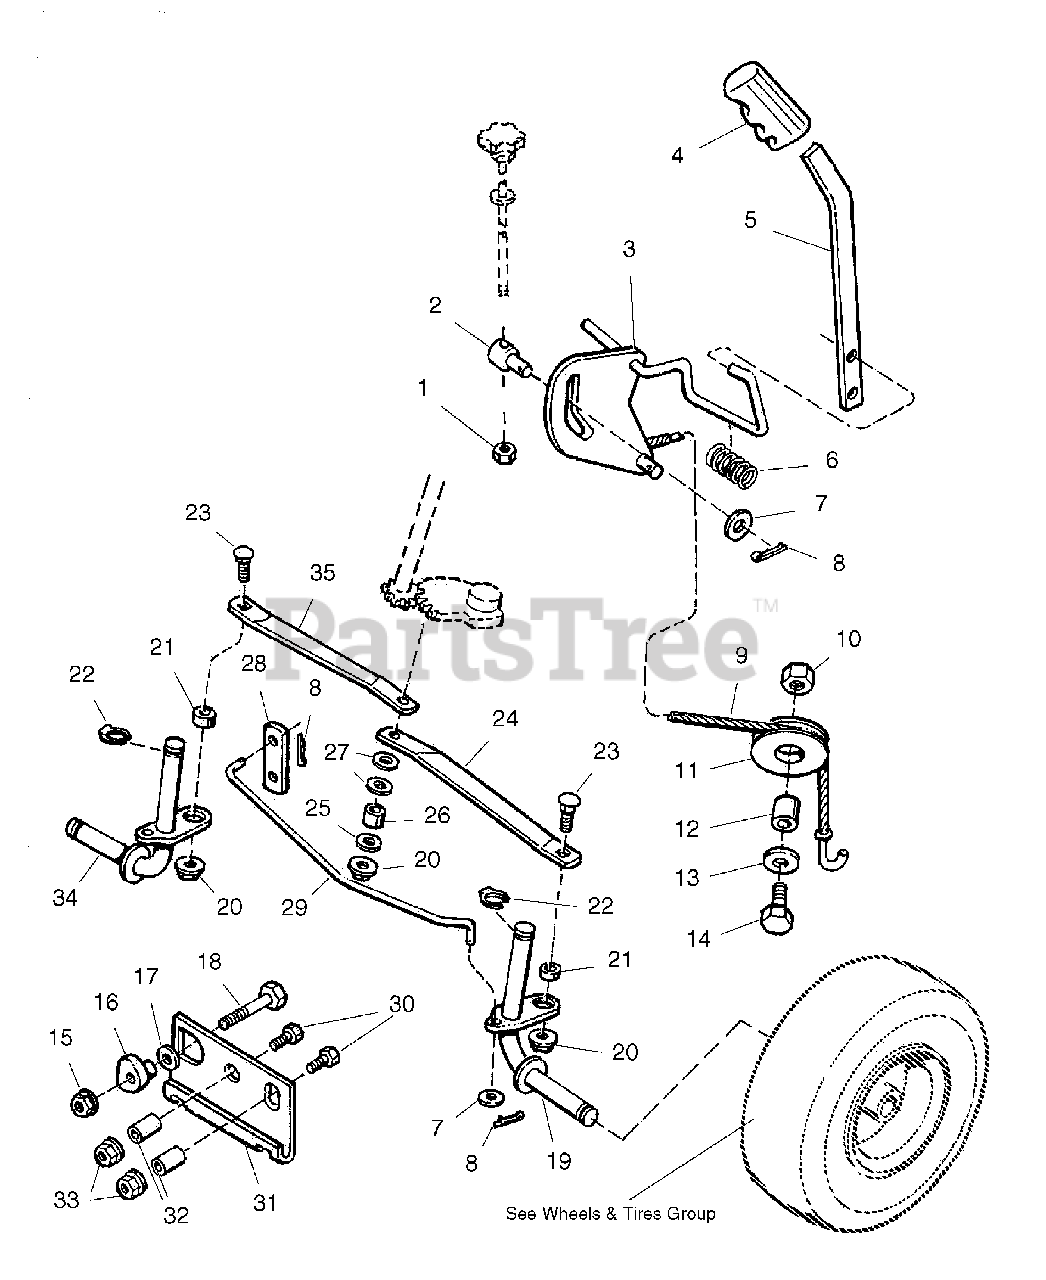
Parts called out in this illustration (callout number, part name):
1	NUT, Hex, 3/8-16
3	ARM ASSEMBLY, Lift
4	GRIP, Lever
5	LEVER, Lift
6	SPRING, Compression
7	WASHER, Plain, 13/32 x 7/8 x 5/64
8	COTTER PIN, 3/32 x 3/4
9	CABLE ASSEMBLY, Lift
10	NUT, Hex, Esna Lock, 3/8-16
11	PULLEY, Lift
13	WASHER, Plain, 13/32 x 1-1/2 x 1/8
14	CAPSCREW, Hex Head, 3/8-16 x 1-1/2
15	NUT, Hex, Flange Lock, 3/8-16
17	WASHER, 13/32 x 7/8 x 1/8
18	CAPSCREW, Hex Head, 3/8-16 x 1-3/4
19	SPINDLE ASSEMBLY, LH
20	NUT, Hex, Flange Lock, 5/16-18
23	CARRIAGE BOLT, 5/16-18 x 1-1/4
24	TIE ROD, LH
25	WASHER
26	SPACER, 21/64 x 1/2 x 5/8
27	WASHER
30	CAPSCREW, Hex Head, 1/2-13 x 1-1/2
31	HITCH, Hook
33	NUT, Hex, Flange Lock, 1/2-13
34	SPINDLE ASSEMBLY, RH
35	TIE ROD, RH
